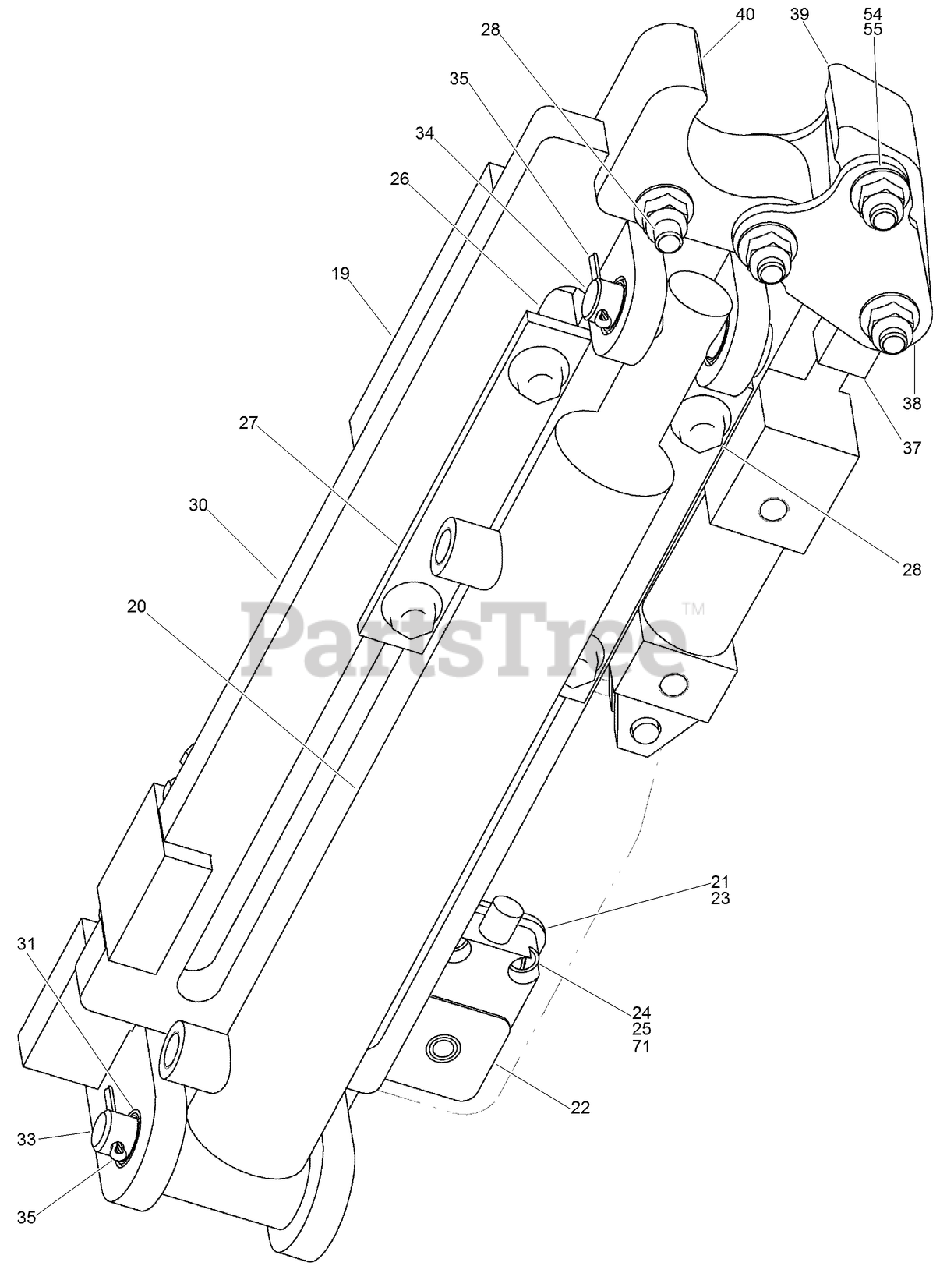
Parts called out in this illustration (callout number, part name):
19	ASSEMBLY - Extension Arm
20	HYD CYLINDER ASM
21	BRACKET-SENSOR, EXTENSION ARM
22	SWITCH-PROXIMITY
23	SCREW, METRIC FLANGE w/BODY - M8 x 20
24	WASHER - 0.203 x 0.469 x 0.049 in CST ZND
25	NUT - Prev Trq # 10 GRB ZND Insert
26	PLATE - Guide
27	PLATE - Cap
28	SCREW, METRIC FLANGE w/BODY - M10 x 60
30	ASSEMBLY - Slider Extension
31	BUSHING-SPRING
33	PIN - Clevis
34	PIN-CLEVIS
35	PIN-Cotter, 1/8 x 1-1/4 in ZN
37	ROD-EYE, CYLINDER
38	PLATE-GRIPPER, ROTATE
39	INSERT-GRIPPER, ROTATE
40	INSERT-GRIPPER, FIXED
54	SCREW-HHF
55	NUT-FLANGE, NYLOCK
71	SCREW - Phd Sltd #10-24 x 1.00 CST ZND
